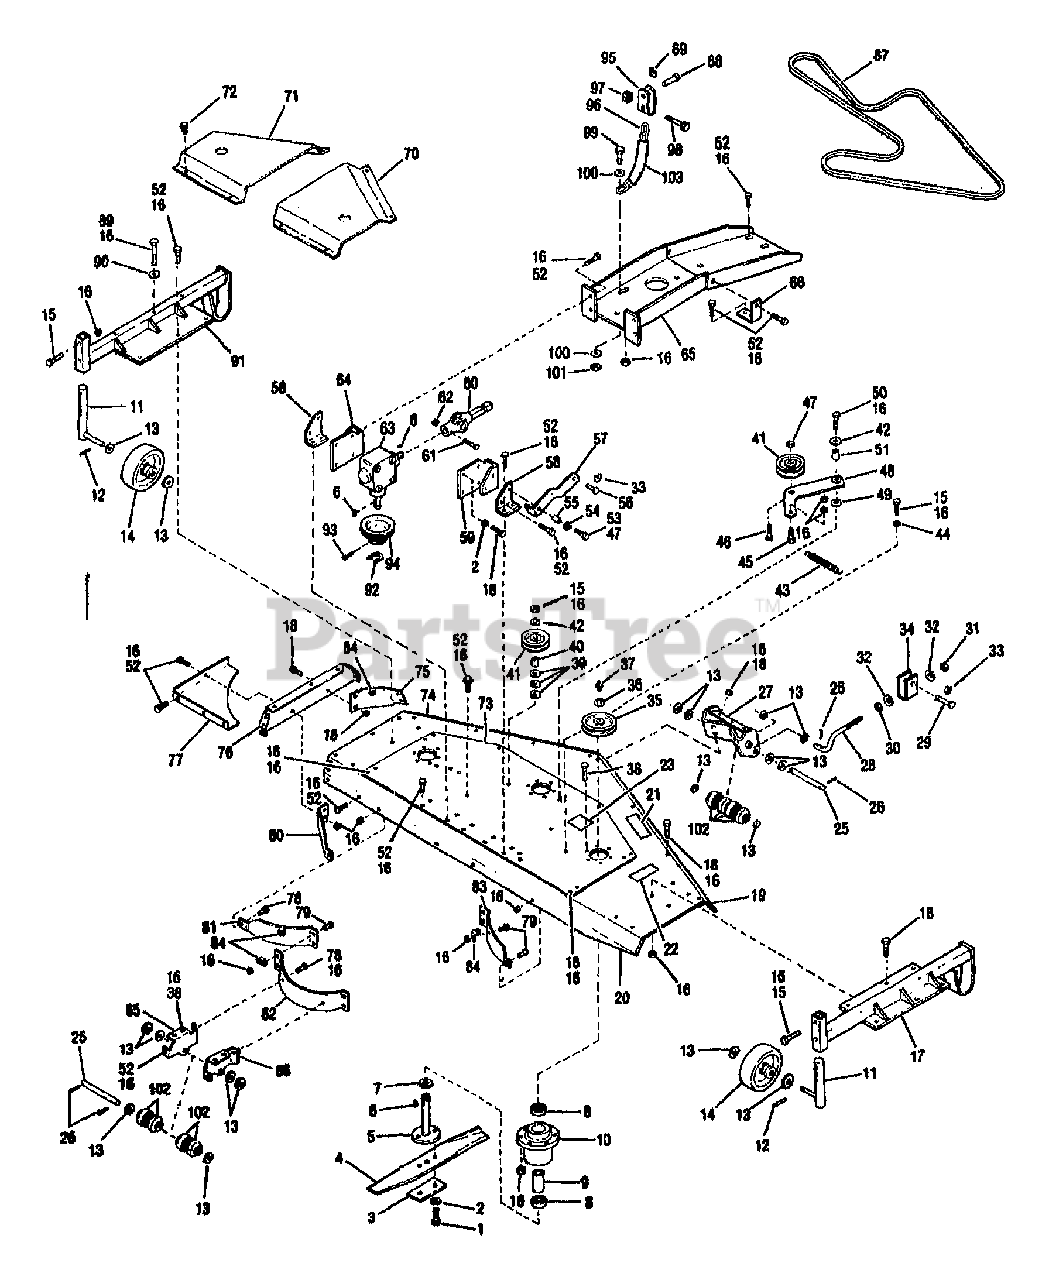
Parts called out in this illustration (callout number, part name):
1	SCR-HH 3/8-24X1.0 G5 ZP
2	WASHER-LK .375 @ DEPL
3	PLATE-BLADE
5	ASSM-BLADE SHAFT
6	KEY-WOODRUFF .25X.875
7	SHIM-1.25X1.01X.06
8	BEARING-BALL
9	SLEEVE
10	HOUSING-SPINDLE
11	ASSM-REAR AXLE
12	PIN-DRIVE
13	WASHER-1.5X.812X.134 ZP
14	GAUGE-WHEEL
15	SCR-HH 3/8-16X2.0 G5 ZP
16	NUT-LOCK 3/8-16
17	SUPT-GAGE WHEEL RH
18	SCR-HH 3/8-16X.75 G5 ZP
19	BASE-FRONT RH
20	ASSM-BASE W/DECAL
21	DECAL-OPEI CAUTION
22	DECAL-CUTTING LINE
23	DECAL-BELT DRIVE
25	SHAFT-ROLLER
26	PIN-COTTER .120X1.25 ZP
27	ASSM-BRKT FRONT DRAG
29	PIN-CLEVIS .62X2.50 ZP
30	NUT
31	NUT .750-10
32	WASHER-LK 1.264X.76X.188
33	RING-COTTER
34	ASSM-HITCH BRKT
35	SHEAVE-BLADE
36	NUT-SELF LOCK
37	FITTING-GREASE 1/4-28X2.00
38	SCR-HH 3/8-16X1.25
39	WASHER-1.12X.378X.125
40	SPACER-.5X.385X.437
41	PULLEY-IDLER
42	WASHER-.986X.437X.083 ZP
43	SPRING-EXTENSION
44	NUT-HEX/JAM 3/8-16
47	BRACKET-ACTUATOR
48	ASSM-IDLER ARM
49	WASHER
50	SCR-HH 3/8-16X1.5 G5 ZP
52	SCR-HH 3/8-16X1.0 G5 ZP
53	SCR-HH 1/2-13X1.75 G5 ZP
54	WASHER-1/2 FLAT
55	SPACER-TUBULAR
56	PIN-CLEVIS .625X1.44
58	BRKT-MOUNTING
59	BRKT-GEAR BOX RH
61	SCR-HH 1/4-20X2.0 G5 ZP
62	NUT-HT LK 1/4-20
63	RIGHT ANGLE GEAR BOX ASSY
64	BRKT-GEAR BOX LH
65	ASSM-BASE BRIDGE
66	BRKT-SUPPORT
68	PIN-CLEVIS .375 X .937 ZP
69	RING-CIRCLE COTTER
70	COVER-BELT RH
71	COVER-BELT LH
72	SCR
73	BASE-DOUBLE
74	BASE-FRONT LH
75	BAFFLE-FRONT CORNER
77	PLATE-BAFFLE
78	SCR-CARR 3/8-16X1.00
79	BOLT-3/8-16 X 3/4
80	BAFFLE-REAR CORNER
82	BAFFLE-CENTER
84	BRKT-BAFFLE
87	BELT-V
89	SCR-HH 3/8-16X2.75 G5 ZP
90	WASHER-FLAT 1.25X.406X.179
91	SUPT-GAGE WHEEL LH
92	RING-RETAINING
93	SCR-SQ HD SET 5/16X3/4
94	SHEAVE-DRIVE
96	KIT-CHAIN
97	NUT-H/LK 5/16-18
98	SCR-HH 5/16-18X1.25 G5ZP
100	WASHER-FLAT 5/16 SAE
101	NUT-TOP/LK 5/16-18 ZP
102	ROLLER
103	SLEEVE-CHAIN
